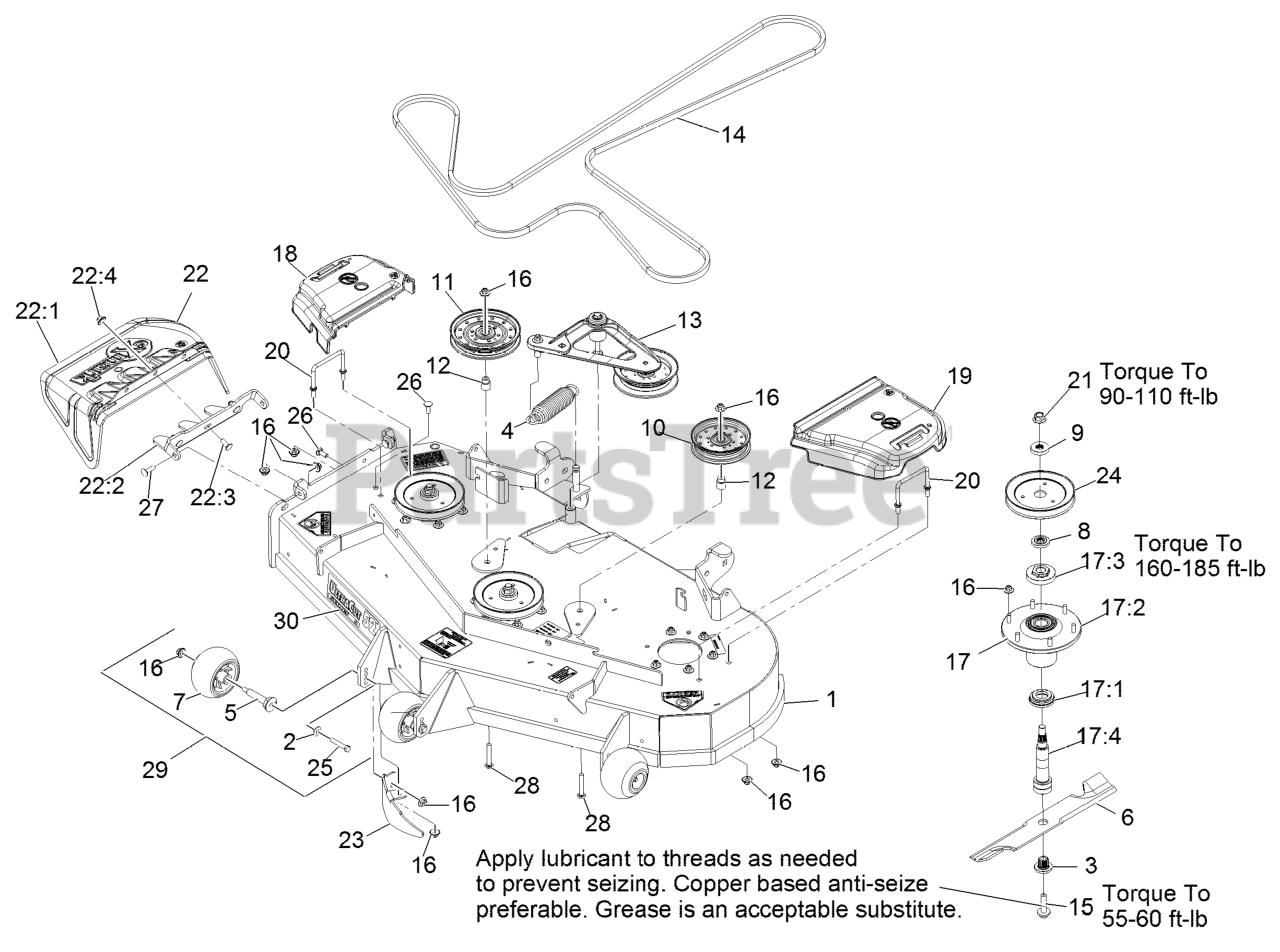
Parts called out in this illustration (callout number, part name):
1	ASM,DECK W/ DECALS 52
2	WASHER-BELLEVILLE
3	BUSHING,SPLINED
4	SPRING-EXTENSION
7	ROLLER-SCALP, ANTI
8	SPACER,SPLINED STEPPED
9	SPACER,SPLINED
12	BUSHING-IDLER
13	DECK IDLER ASM
14	BELT,V-B X 186.00"
15	SCREW,SEMS 1/2-20 X 2.19
16	Nut-Nyloc 3/8-16 Flg
17	ASM,SPINDLE HOUSING
17:1	GUARD,BOTTOM
17:2	ASM,CUTTER HOUSING
17:3	NUT, SPINDLE 7/8-14
17:4	SPINDLE,DOUBLE SPLINE
18	COVER-BELT, RH
19	COVER-BELT, LH
20	WIREFORM-COVER
21	NUT-FLANGE, CENTERLOCK
22	ASM,DISCHARGE CHUTE
22:1	CHUTE,DISCHARGE
22:2	BRACKET,DISCHARGE CHUTE
22:3	SCREW-CARR
22:4	Nut-Nyloc 3/8-16 Flg
23	BAFFLE-DOGLEG, LZ-VT52
24	SHEAVE,BLADE DRIVE
25	SCREW-HH
26	SCREW-CARR
27	Bolt-Carriage 3/8-16 X 1 1/4
28	SCREW-CARR
30	DECAL,ULTRACUT 52 SERIES
